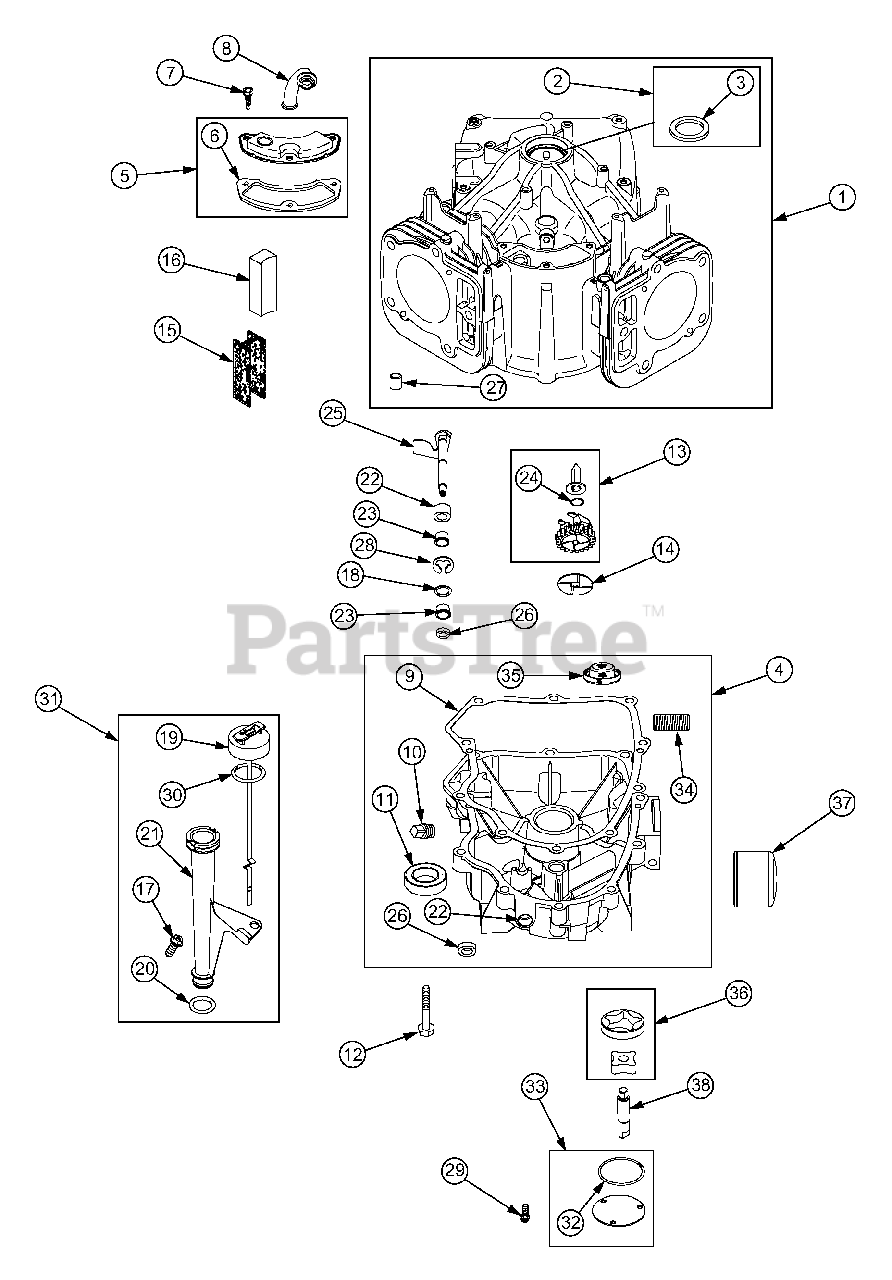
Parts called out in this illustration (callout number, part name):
1	Cylinder Assembly
2	Kit, Bushing/Seat (Magneto Side)
3	Seal, Oil (Magnetor Side)
4	Sump, Engine
5	Breather Assembly
6	Gasket, Breather
7	Screw, Breather Assembly
8	Tube, Breather
9	Gasket, Crankcase
10	Plug, Oil Drain
11	Seal, Oil (PTO Side)
12	Screw, Engine Sump
13	Gear, Governor
14	Washer, Governor Lever
15	Retainer, Breather
16	Collector, Oil
17	Screw, Dipstick Tube
18	Washer, Governor Crank
19	Dipstick
20	Seal, Dipstick Tube
21	Tube, Dipstick
22	Bushing, Governor Crank
23	Bushing, Governor Crank
24	Retainer, Governor Shaft
25	Crank, Governor
26	Seal, Governor Shaft
27	Pin, Locating
28	Retainer, E-ring
29	Screw, Oil Pump Cover
30	Seal, Dipstick Tube
31	Dipstick Tube Assembly
32	Seal, O-ring (Oil Pump Cover)
33	Cover, Oil Pump
34	Nipple, Oil Filter
35	Screen, Oil Pump
36	Pump, Oil
37	Filter, Oil
38	Shaft, Pump
